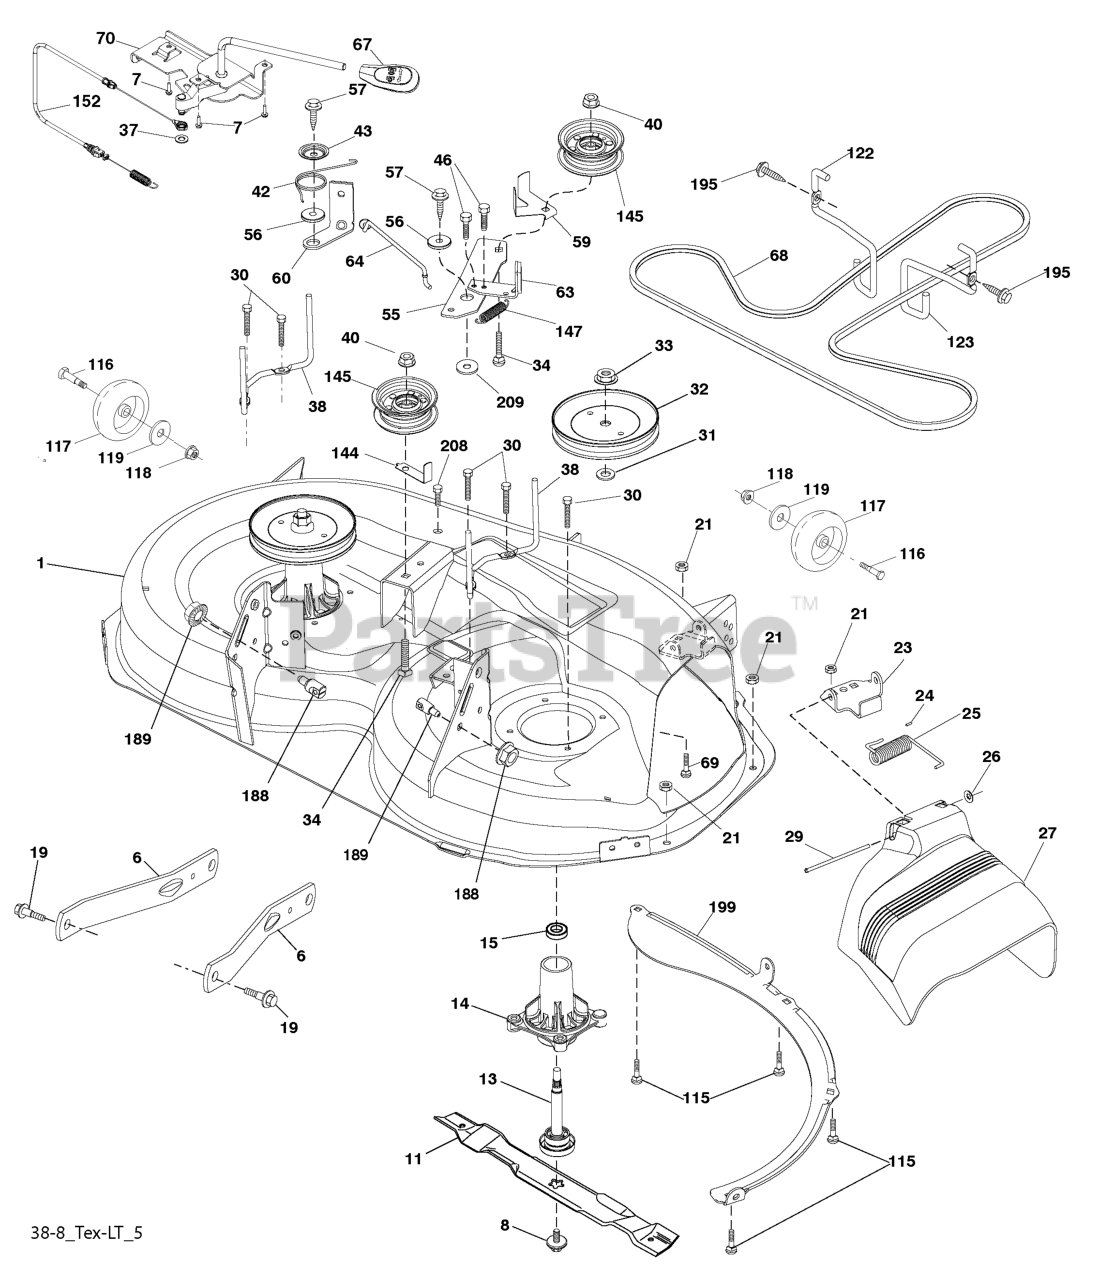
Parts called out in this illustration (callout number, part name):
1	MOWER HOUSING
6	ARM.SUSPENSION.MOWER.R
7	SCREW.#10 X 0.750.BOS
8	BOLT.WASHER.ASM.7/16-2
11	BLADE 38" PREMIUM
13	SHAFT.ASM.MDRL.N/GREASE.38
14	RP.HOUSING.MANDREL.4PT.
19	BOLT.SHOULDER
21	LOCKNUT
23	BRKT.DEFLECTOR.38"2005+
24	CAP-SLEEVE LT
25	SPRING.TORSION.DEFLECT
26	NUT PUSH M
27	SHIELD, DEFLECTOR
29	ROD.HINGE
30	SCREW, WASHER HEAD
31	WASHER.SPACER.MANDREL
32	PULLEY.MANDREL.5.0.PD.38"
33	NUT.FLANGE.LOCK.TOP
34	BOLT.3/8-16X1.50
37	WASHER
38	KEEPER BELT LH MANDREL
40	NUT LOCK FLG 3/8-16 UNC
42	SPRING.TORSION.BRAKE
43	SRPING.TORSION.RETAINE
46	SCREW.1/4-20X5/8
55	IDLER.ARM
56	SPACER.RETAINER
57	SCREW 3/8-16X1
59	GUARD, BELT
60	ARM BRAKE MOWER RH 38"
63	RP ARM.BRAKE.MOWER.38"LH.TEX
64	LINKAGE.BRAKE.ASM.ZINC
67	HANDLE.CLUTCH.CABLE.LT
69	BOLT
70	CLUTCH.ASM.MANUAL.LT.PRED
115	BOLT.CARR.5/16-18X5/8.SHORT
116	BOLT M
117	WHEEL.GAGE.HALF.SPOKED
118	LOCKNUT
119	WASHER.5/16.FLAT.STE.STD.
122	KEEPER BELT ENGINE LH
123	KEEPER BELT RH
144	KEEPER BELT
145	PULLEY.IDLER.48"PRIMARY
147	SPRING RETURN
152	CABLE.CLUTCH.MANUAL.
188	STUD.FASTNER.W/ANTI-ROTATE
189	NUT LOCK HEX FLANGE 5/16-18
195	SCREW, 3/8-16X3/4
199	BAFFLE.VORTEX.FRONT.38"
208	SCREW 3/8-16X1/2
209	WASHER 12/32X2X10GA
